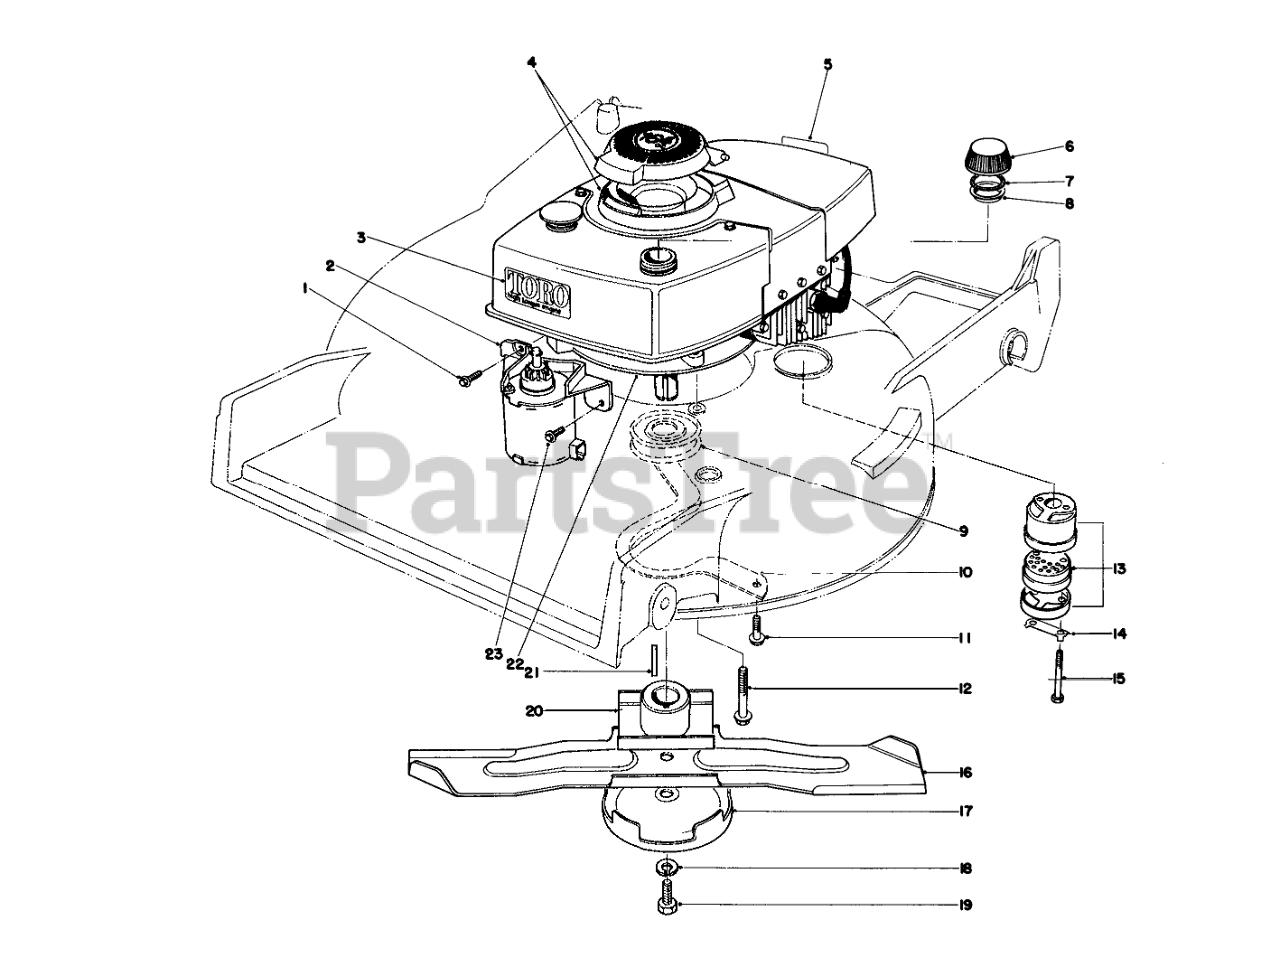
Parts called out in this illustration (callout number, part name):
1	Screw
2	Starter Motor
3	High Torque
4	COVER ASM
5	Decal-Maintenan
6	Gas Cap (Incl. Ref. #7 & 8)
7	GASKET
8	GAS CAP BAFFLE
9	DRIVER PULLEY
10	Belt Guide
11	Screw
12	SCREW-HWHTF
13	Muffler Assy. (Incl. Ref. #14&15)
14	CLIP - LOCKING
15	SCREW-HH
16	Blade
17	AntiScalp Cup
18	WASHER-LOCK
19	BLADE SCREW
20	BLADE RETAINER WA(BLACK)
21	KEY-SQUARE
22	Engine
23	SCREW
